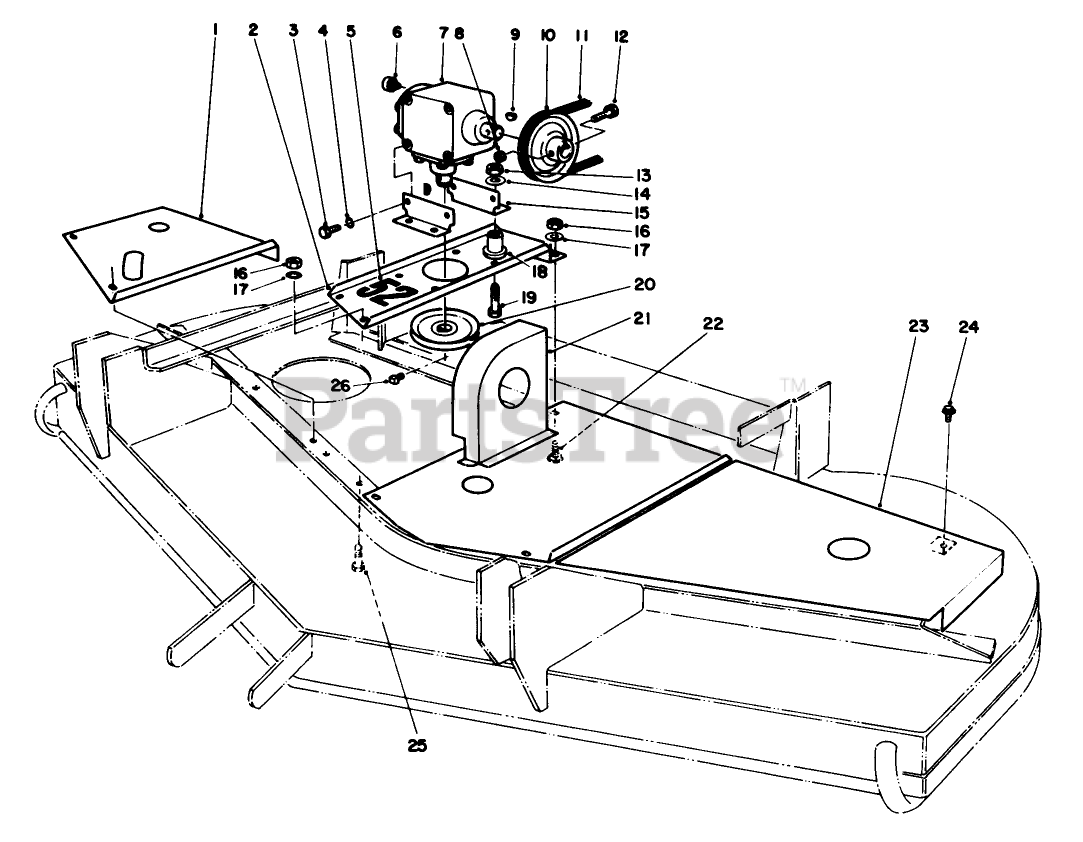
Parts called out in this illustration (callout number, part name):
1	RH COVER WA R
2	GEARBOX BASE
3	SCREW-HH
4	WASHER-LOCK
5	DECAL
6	FITTING-LUBE
7	Gear Box
8	NUT-LOCK, NI
10	PULLEY
11	V-BELT, DECK
12	SCREW-HH
13	NUT-LOCK, SIDE
14	WASHER
15	Bracket Mounting
16	NUT-LOCK, NI
17	WASHER-FLAT
18	MOUNT
19	SCREW-HH
20	PULLEY
21	CENTER COVER WA R
22	BOLT-CARR
23	LH COVER WA R
24	SCREW-HHFTF
25	SCREW-HH
26	SCREW-SET, SQH
